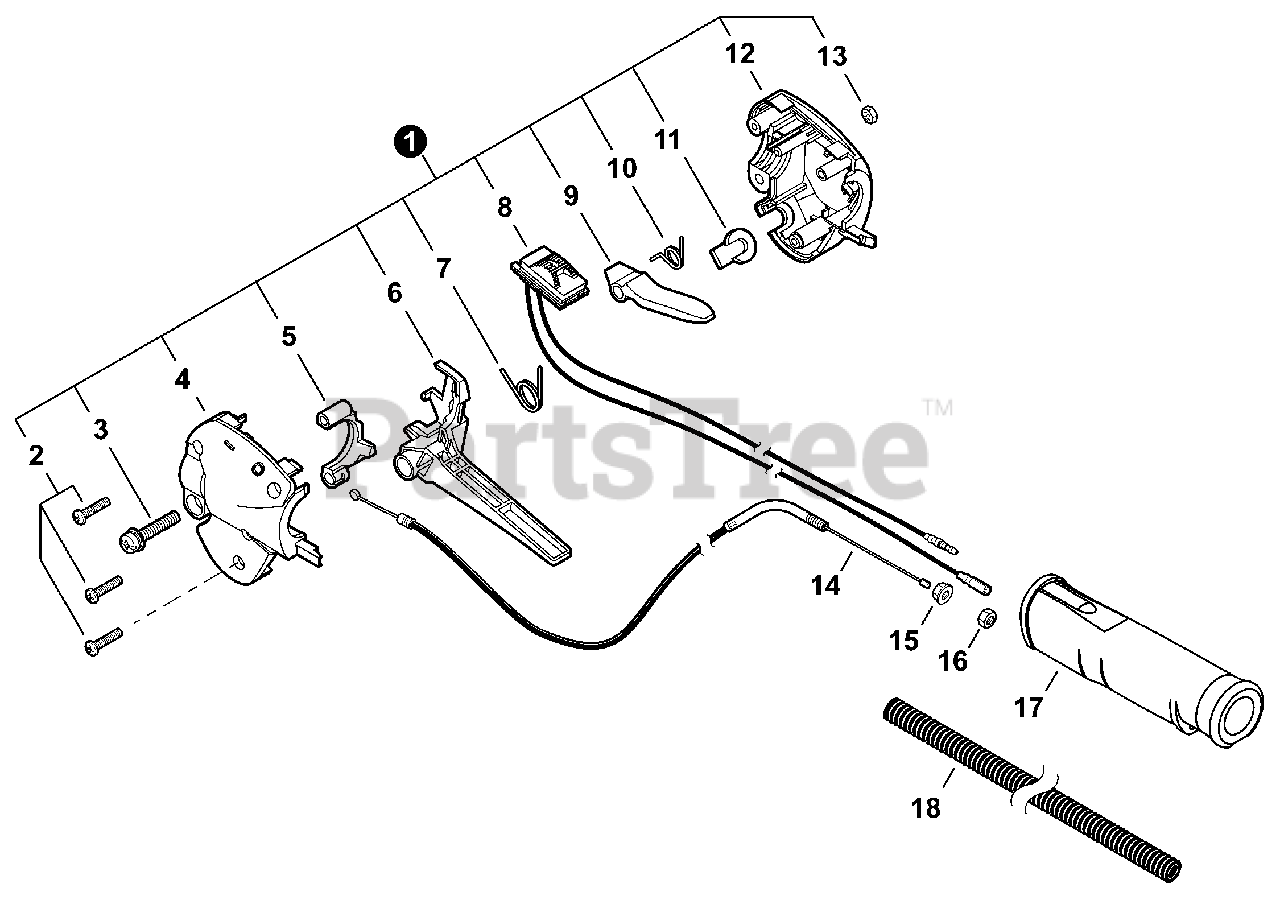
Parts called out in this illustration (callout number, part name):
1	THROTTLE CONTROL ASSY
3	BOLT, TORX 5×16
4	CONTROL HANDLE - LEFT
5	LOCKOUT, THROTTLE
6	TRIGGER, THROTTLE
7	SPRING, THROTTLE RETURN
8	SWITCH, ON-OFF
9	LEVER, THROTTLE LOCKOUT
10	SPRING, THROTTLE LOCKOUT
12	CONTROL HANDLE - RIGHT
13	NUT - 5
14	CABLE, THROTTLE
15	NUT, FLANGE M6
17	GRIP, HANDLE
18	TUBE, PROTECTIVE
